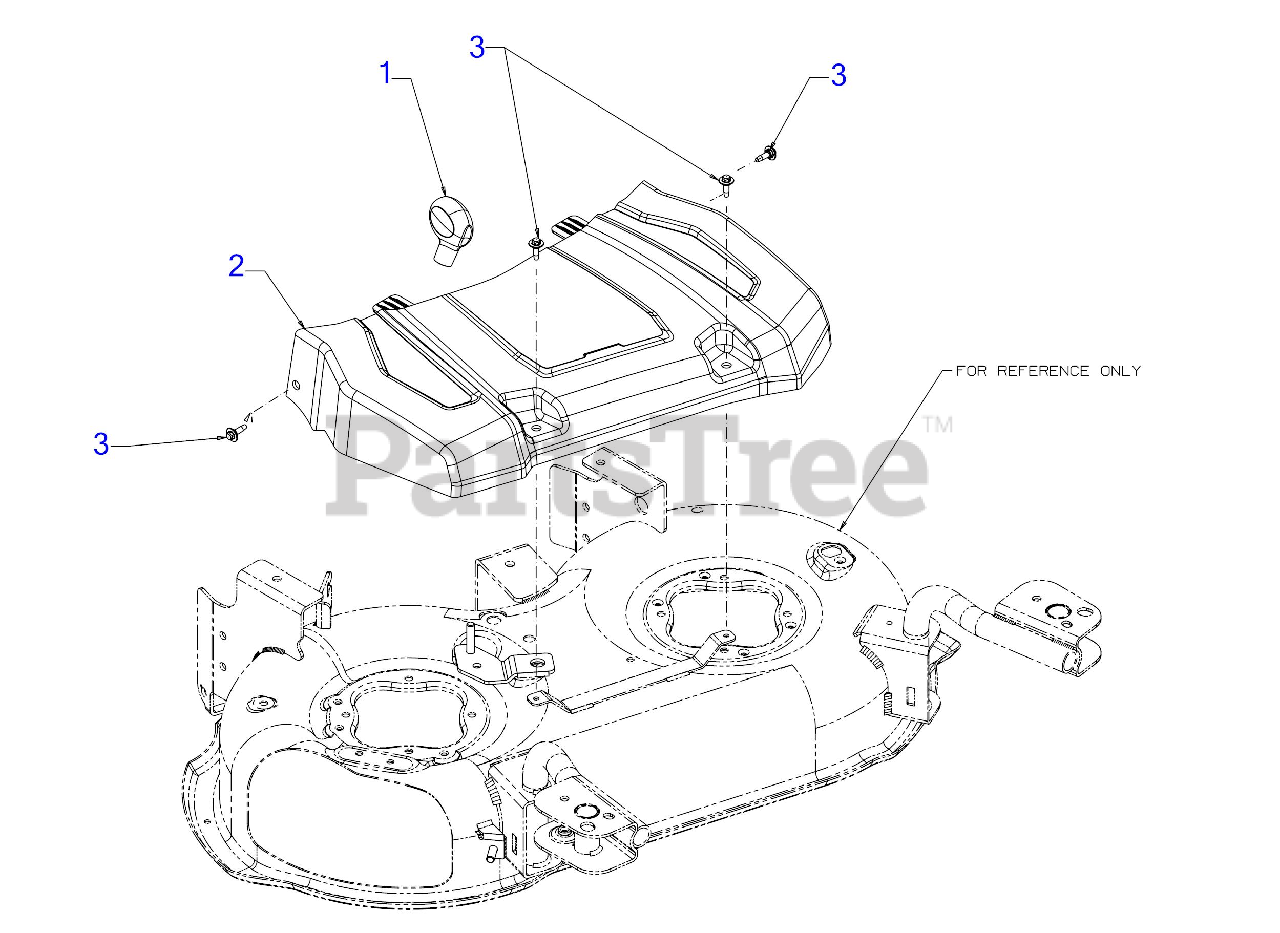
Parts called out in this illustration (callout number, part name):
1	HEIGHT ADJUSTMENT KNOB-RED
2	28" BELT COVER
3	SHOULDER SCREW M6-1 .368 X.115
